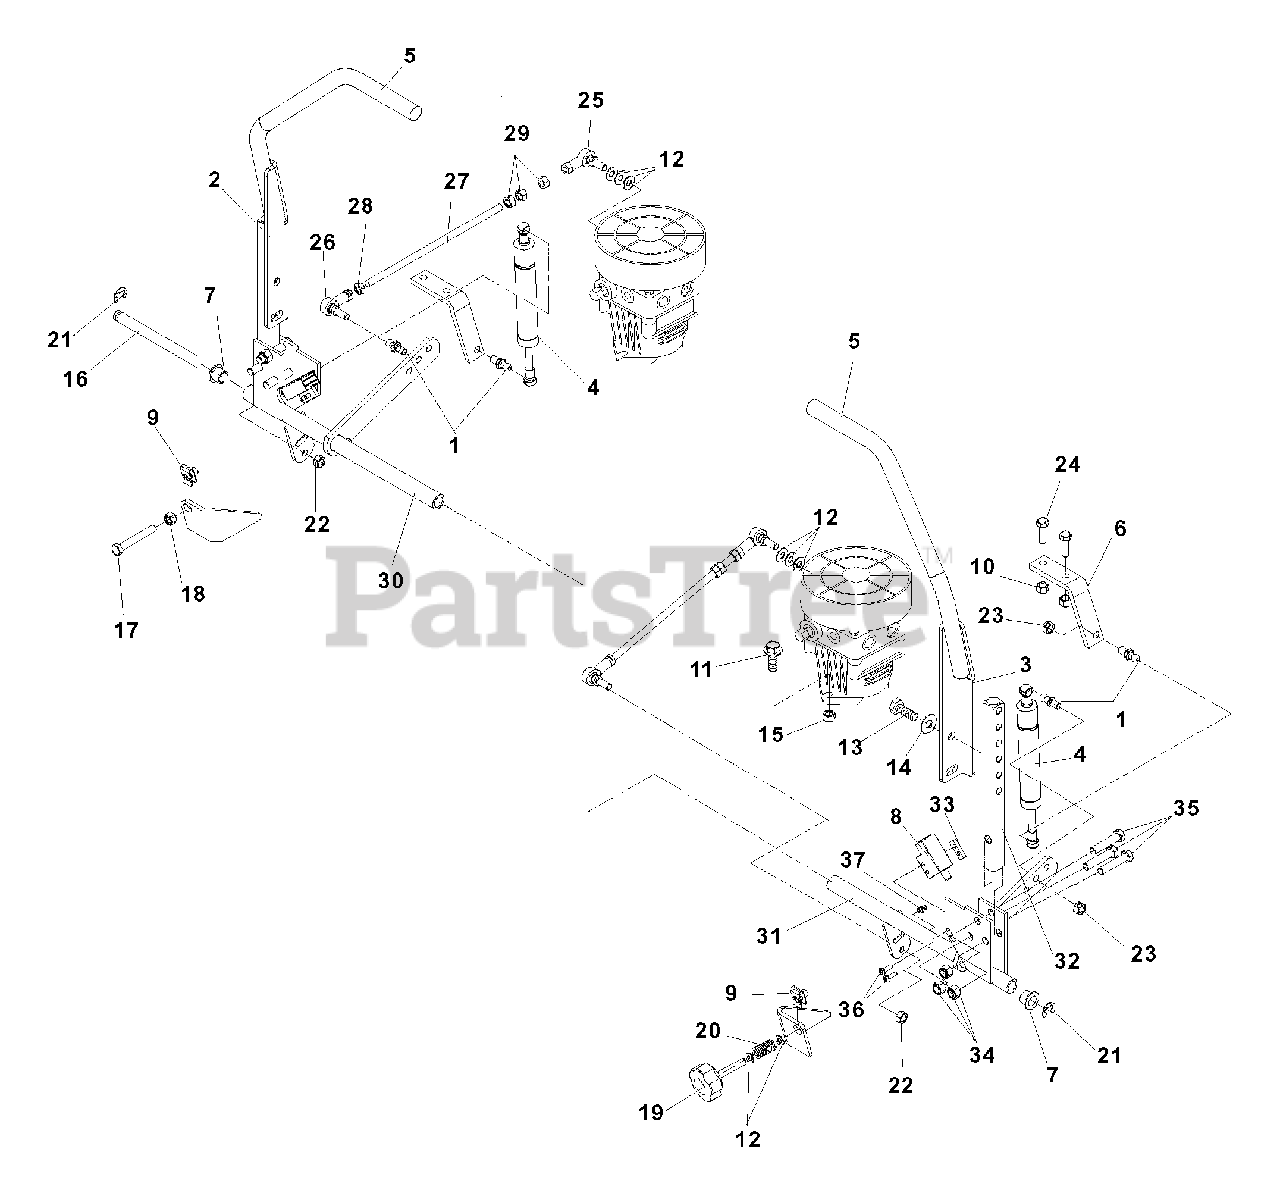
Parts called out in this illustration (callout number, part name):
2	DRIVE LEVER, RIGHT
3	DRIVE LEVER, LEFT
4	DAMPENER
6	DAMPENER BRACKET
8	INTERLOCK SWITCH
9	"U" CLIP, 5/16 C
10	NUT, 5/16 C, NYLOC
11	HFCS, 3/8C x 1
12	WASHER, 5/16
13	HCS, 3/8 C x 1
14	SPRING WASHER, 3/8
15	NUT, 3/8C, CENTERLOCK
16	CONTROL SHAFT
17	HCS, 5/16C x 1 3/4, TAPBOLT
18	NUT, 5/16 C
21	E-RING, 1/2"
22	NUT, 5/16 F, NYLOC
23	NUT, 5/16C, CENTERLOCK
24	HCS, 5/16C x 1
25	ROD END, RIGHT
26	ROD END, LEFT
27	TRACKING LINKAGE
28	NUT, 5/16F, LH, JAM
29	NUT, 5/16F
30	CONTROL, RIGHT
31	CONTROL, LEFT
32	ARM, CONTROL SHAFT
33	TAPPED PLATE
34	NUT, 3/8 -16, NYLOC
35	HCS, 3/8 -16 x 1 3/4, GR5
36	SCREW, #10-24 x 5/8, MACH.
37	ZERK
